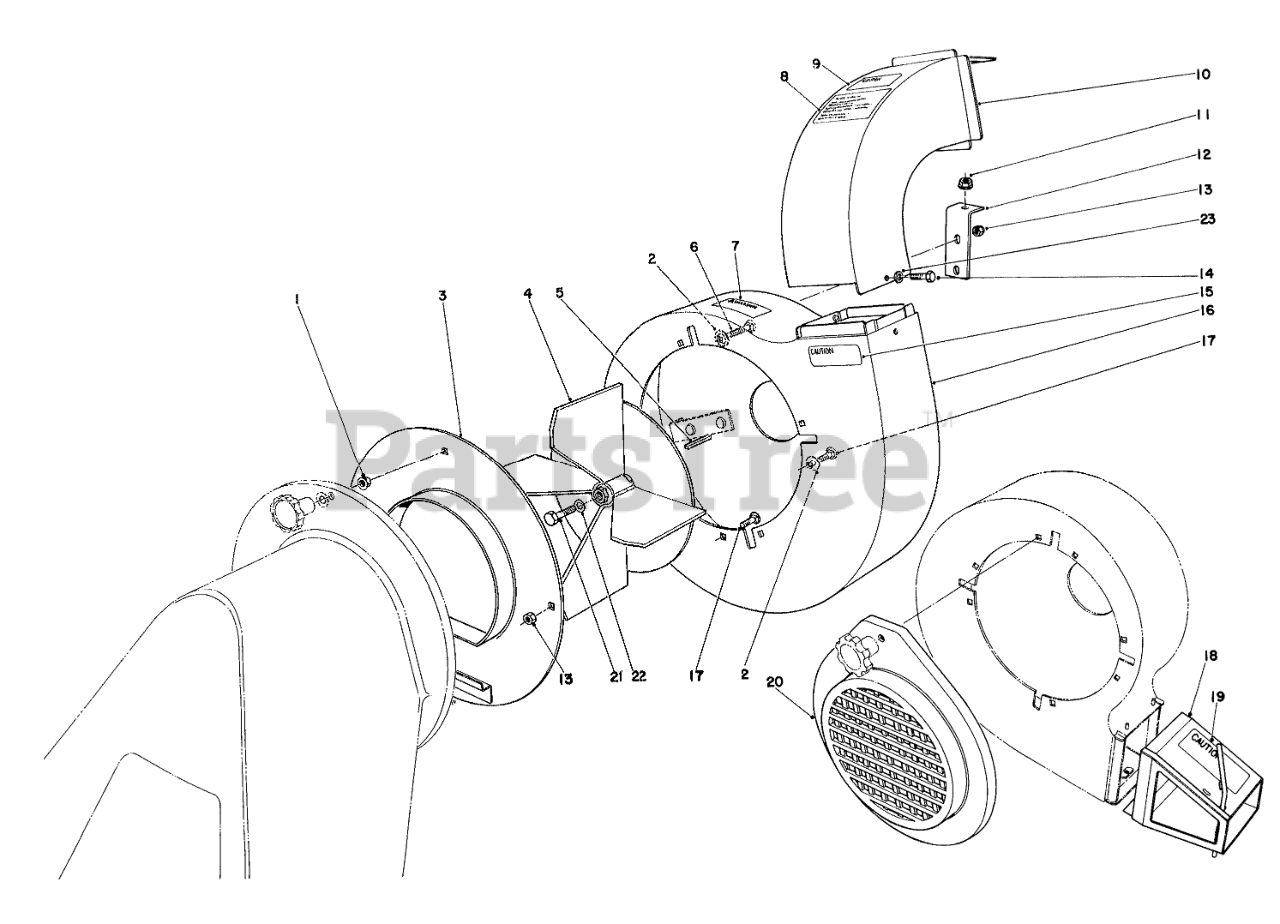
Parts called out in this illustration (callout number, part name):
1	NUT-FLANGE
2	WASHER-FLAT
3	Blower Cover
4	Fan
5	KEY-SQUARE
6	BOLT-CARR
7	ROTATE WARNING DECAL
8	TORO ADVER DECAL
9	DECAL CAUTION BAG
10	Chute-Vacuum
11	NUT-LOCK, NI
12	Bracket-Housing
13	NUT-LOCK, NI
14	SCREW-HH
15	WARNING DECAL
16	Blower Housing
17	SCREW-CARR
18	Blower-Exhaust (Incl Ref.#19)
19	EXHAUST DECAL
20	INTAKE-BLOWER
21	SPEC SCREW
22	WASHER-BELLEVILLE
23	WASHER-BELLEVILLE
